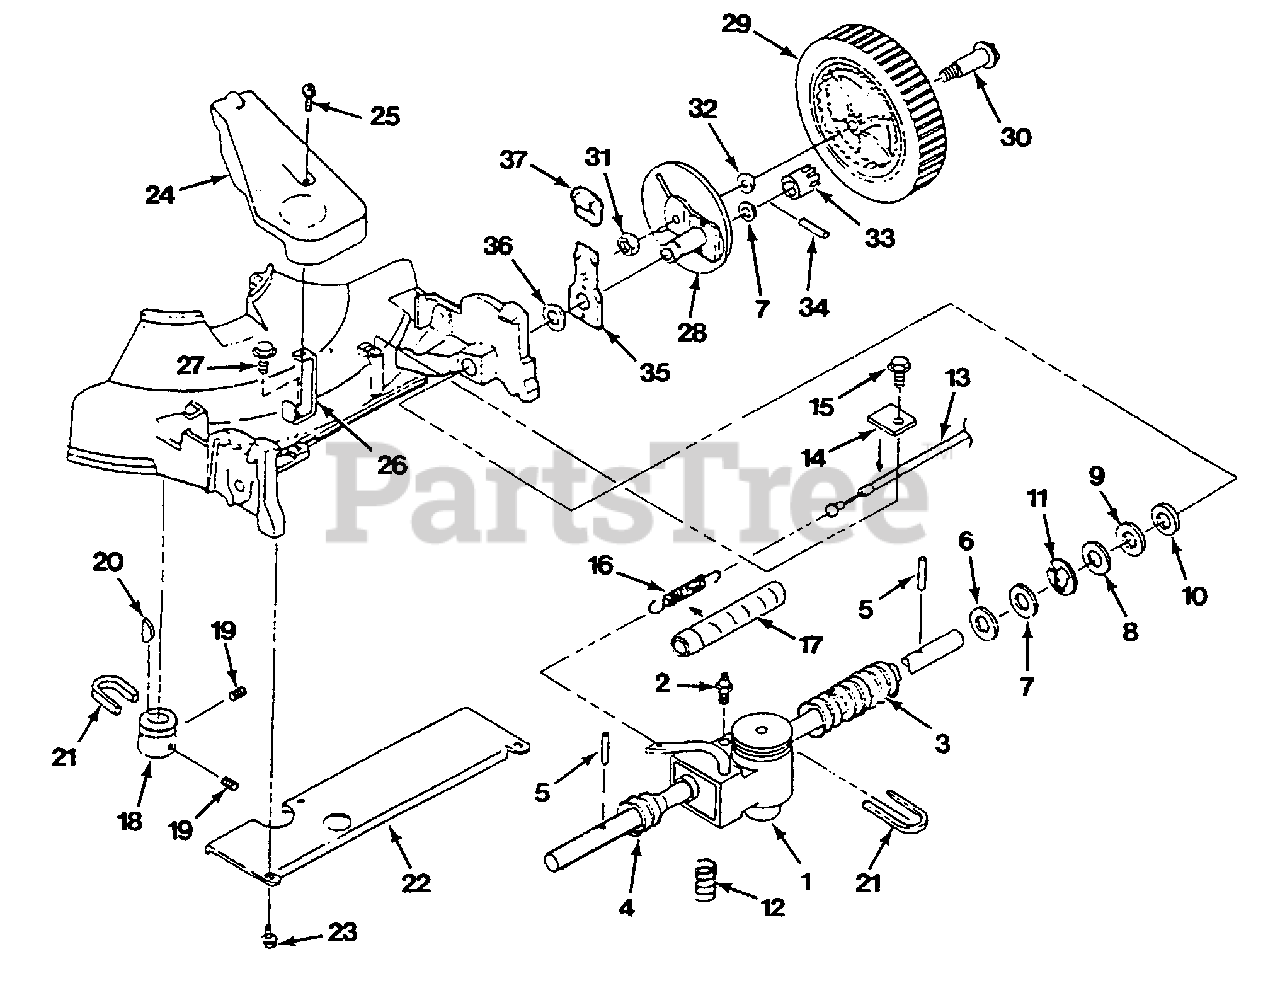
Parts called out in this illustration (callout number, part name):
1	Reducer - gear, complete
2	Vent - gear reducer
3	Cover - axle, long
4	Cover - axle, short
5	Pin - roll 1/8 x 7/8
6	Washer - flat
7	Washer - flat 1/2
8	Washer - flat 1
9	Washer - shim 1
10	Washer - ware
11	Ring - retainer
12	Spring - compression
13	Cable - drive control
14	Clamp - drive cable
15	Screw - hex 1/4-20 x 1/2 tap
16	Spring - extension
17	Cover - spring
18	Pulley - drive
19	Screw - set 1/4-20 x 3/8
20	Key - Woodruff #61
21	Belt - drive
22	Cover - rear
23	Screw - hex 1/4-20 x 3/4
24	Cover - gear reducer
25	Screw - phillips 1/4-20 x 3/4
26	Bracket - cover
27	Screw - hex 1/4-20 x 9/16 tap
28	Support - drive wheel
29	Wheel - 8" w/tire
30	Bolt - wheel w/nut
31	Nut - hex 3/8-16 lock
32	Washer - flat
33	Pinion - drive RH
34	Pin - drive
35	Lever - height adjuster, rear
36	Spacer - adjuster lever
37	Tip - adjuster lever
